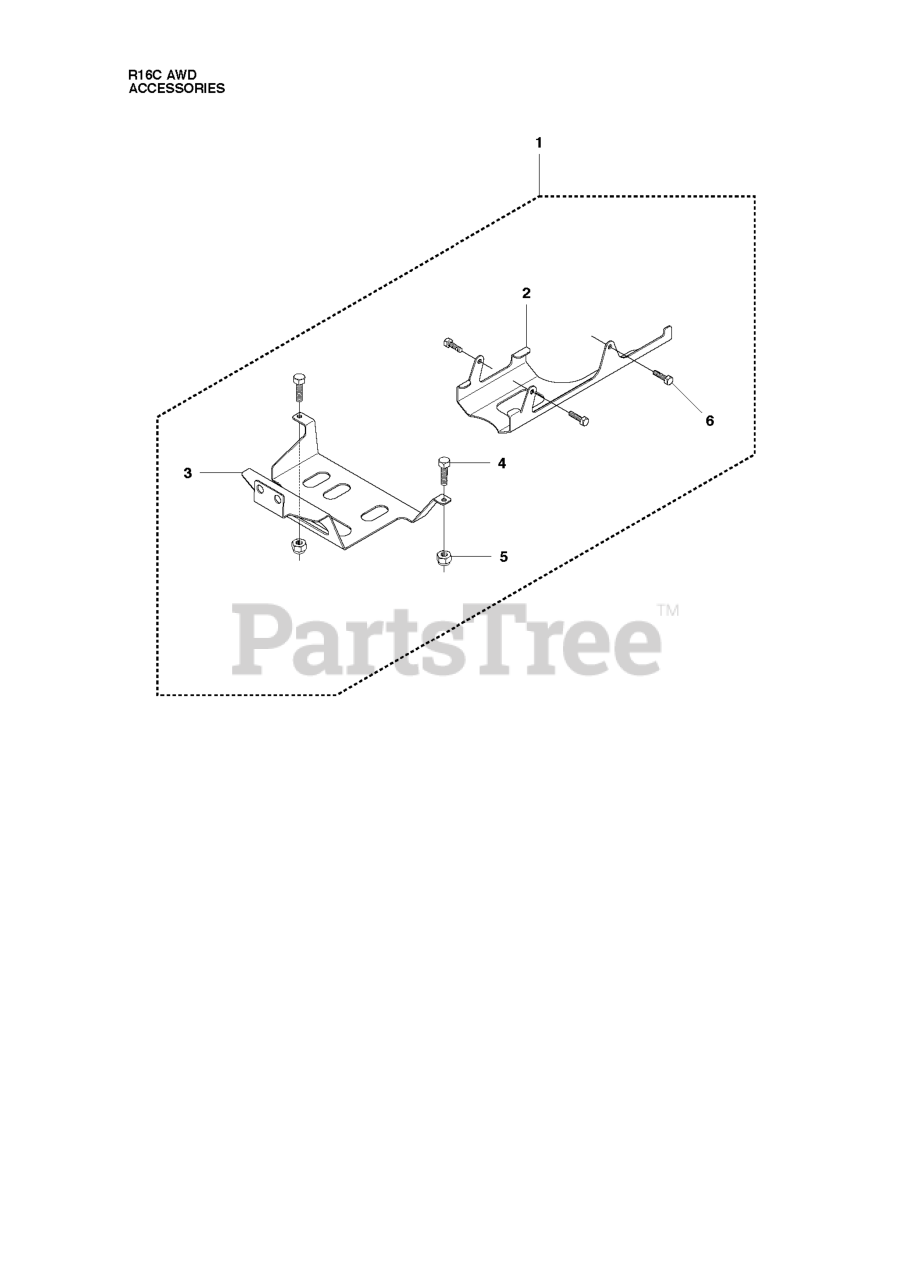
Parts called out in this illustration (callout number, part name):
1	AXLE PROTECTION KIT (R322T)
3	RP PROTECTION PLATE REAR
5	LOCKNUT M8
6	BOLT FLANGE - M8X16
